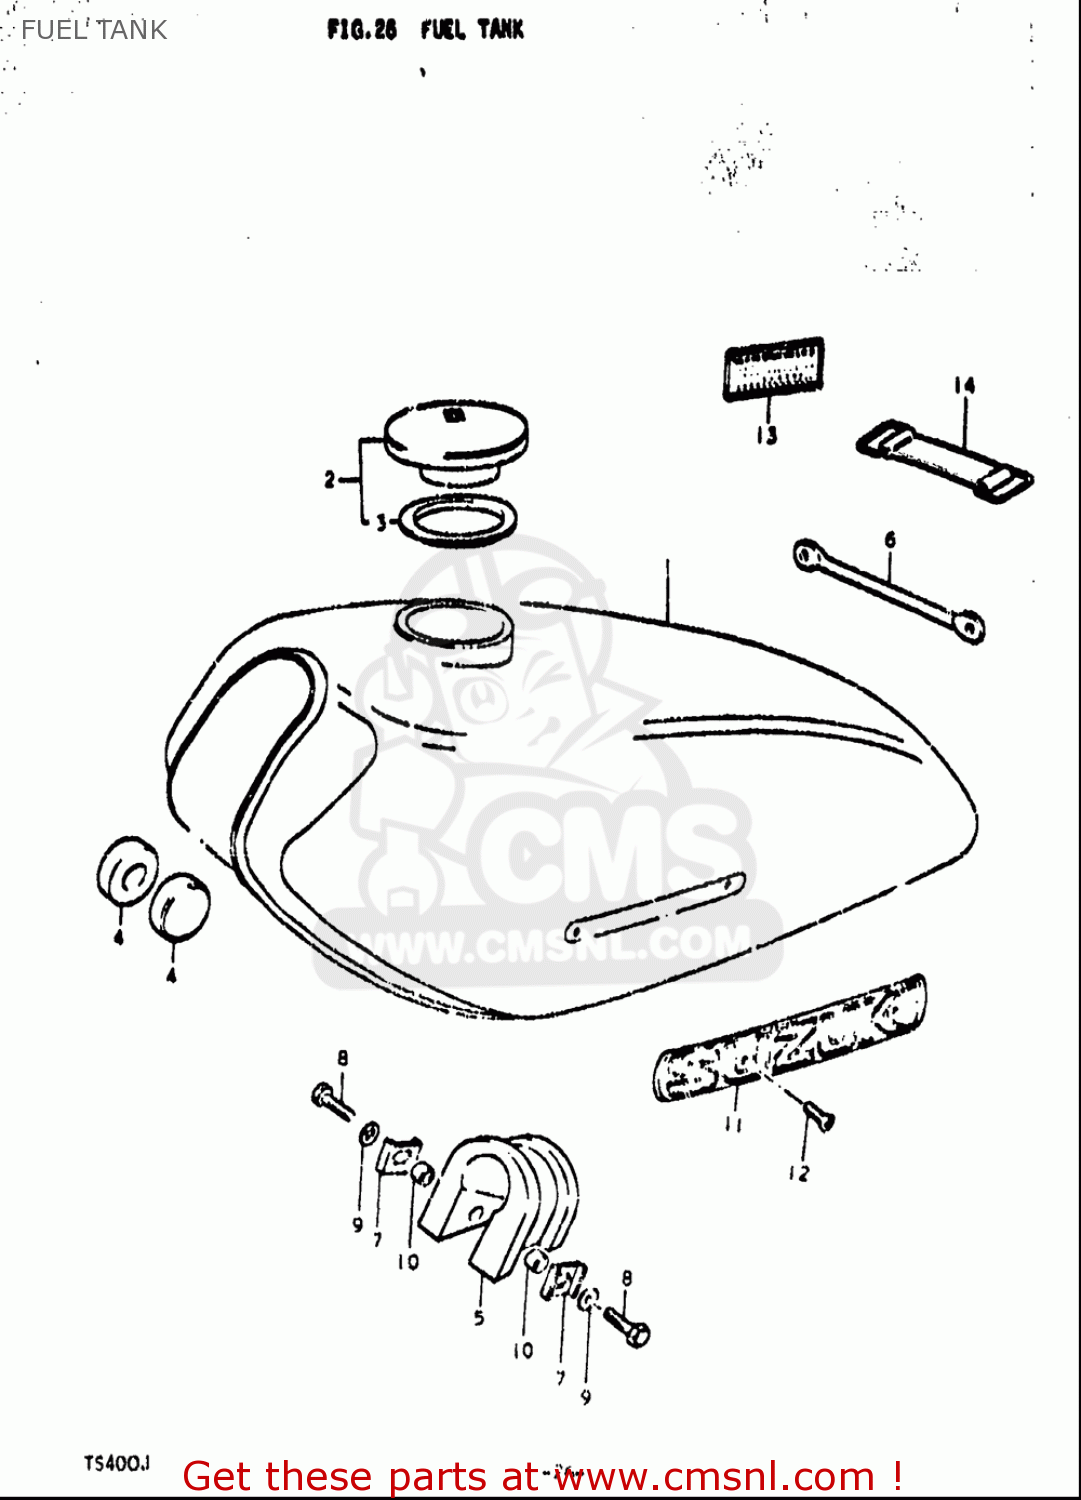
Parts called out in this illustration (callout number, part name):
4	CUSHION
8	BOLT
9	WASHER
10	SPACER(6.1X8X5.2)
12	SCREW
13	CUSHION,FUEL TANK
14	BAND
